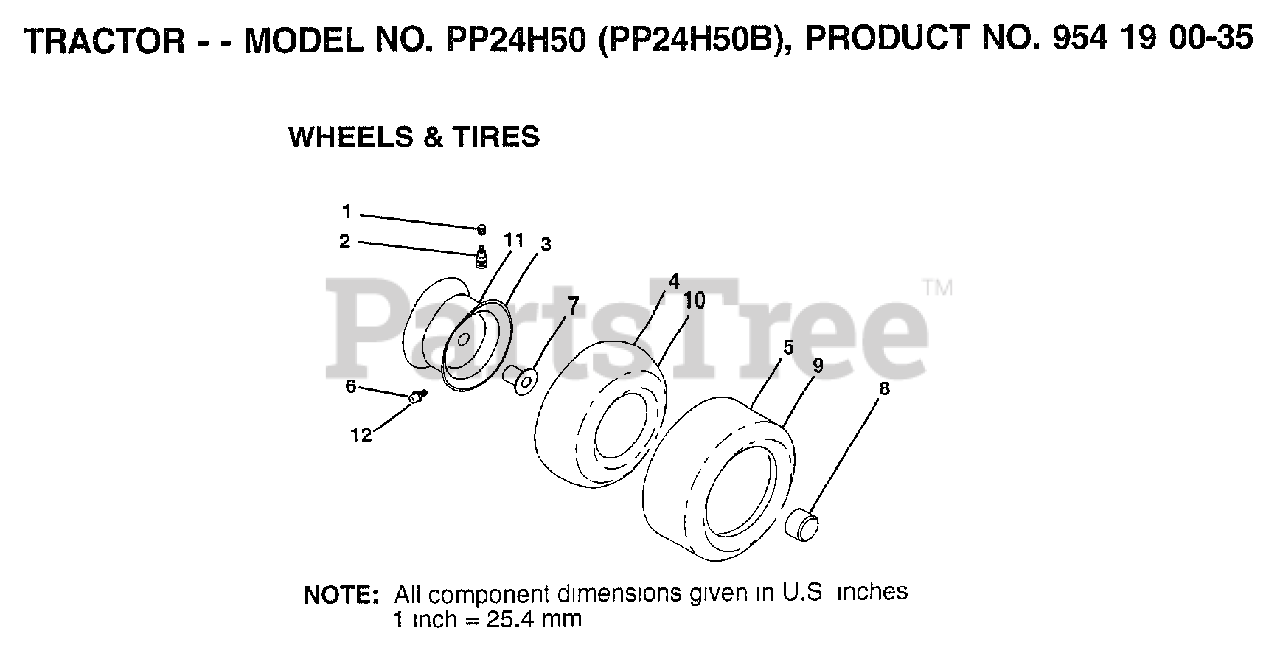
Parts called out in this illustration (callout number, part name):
1	VALVE CAP
2	VALVE STEM LT
3	RIM.FRONT.
4	TUBE.16X6.5/7.5-8
6	FITTING LT
7	"FLANGE, BEARING"
8	HUB CAP
10	TUBE.23X8/10-12
11	"WHEEL,REAR"
12	ZERK FITTING M
